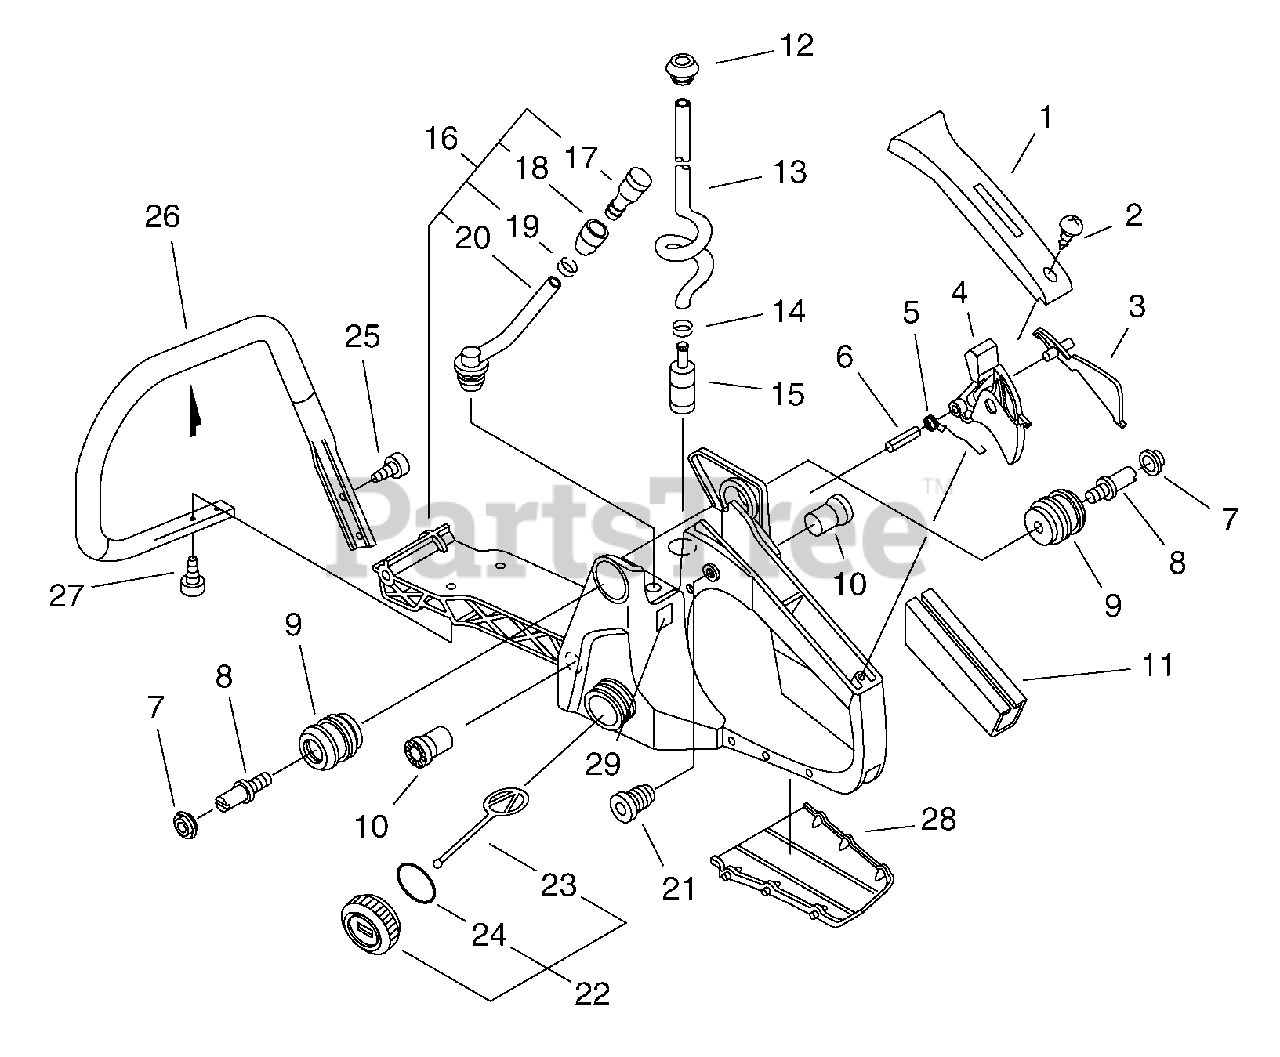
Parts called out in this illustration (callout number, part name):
1	COVER, HANDLE
2	SCREW - 4X14
3	LEVER, TRIGGER LOCKOUT
4	TRIGGER, THROTTLE
5	SPRING, TRIGGER
6	PIN - SPRING -- 4X30
7	CAP, CUSHION
11	GRIP, HANDLE
13	PIPE, FUEL - SPIRAL
14	CLIP - 6.5
15	FILTER, FUEL
16	HANDLE ASSY - REAR
17	VENT, FUEL TANK
18	COVER, VENT
19	CLIP - 6.5
20	PIPE - VENT
22	CAP ASSY
23	CONNECTOR, CAP
24	O-RING - 22
25	SCREW - 5X20 -- TAPPING
26	HANDLE - FRONT
27	SCREW - 5X16
28	SHIELD, SNOW
29	LABEL - STOP
